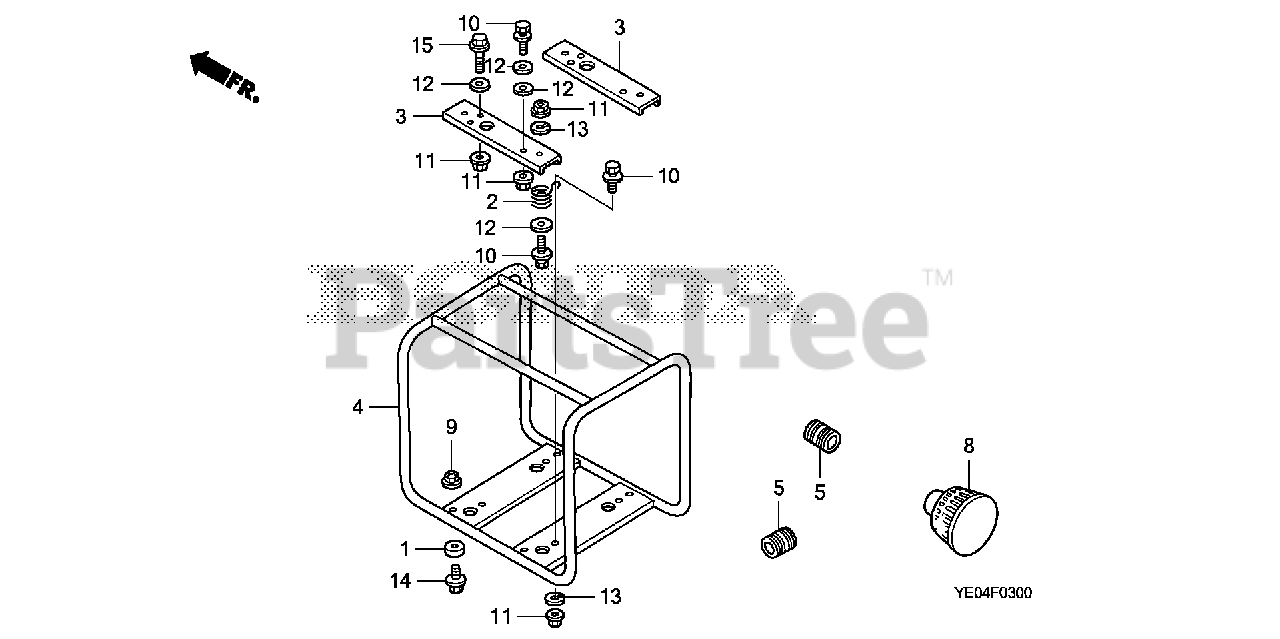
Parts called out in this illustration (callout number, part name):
1	RUBBER (LOWER)
2	SPRING, MOUNTING
3	STAY, MOUNTING
5	COUPLING, HOSE
9	NUT, SELF-LOCK (8MM) (CLINCH)
10	BOLT-WASHER (8X20)
11	NUT, FLANGE (8MM)
12	WASHER, PLAIN (8MM)
13	WASHER, SPRING (8MM)
14	BOLT, FLANGE (8X16)
15	BOLT, FLANGE (8X35)
